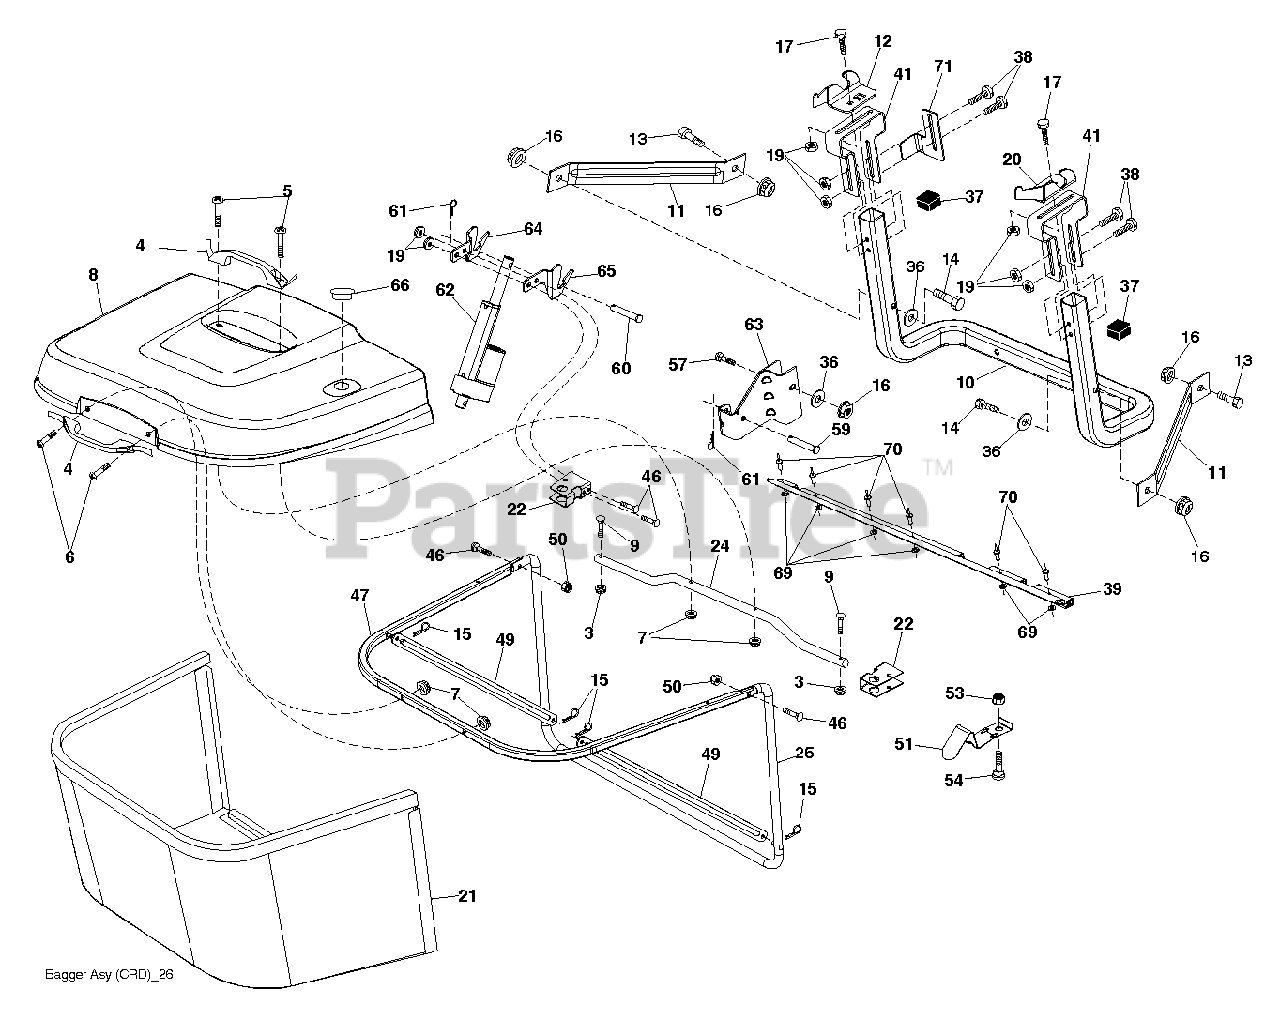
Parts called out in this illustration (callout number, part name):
3	NUT T
5	SCREW.PAN.HEAD
11	BRACKET
14	BOLT-HEX EAK
15	RETAINER-SPRNG RB
16	NUT LOCK FLG 3/8-16 UNC
17	BOLT
19	NUT LOCK HEX FLANGE 5/16-18
20	BRKT.PIVOT.RH.CRD
21	BAGGER.ASM.CRD.2007
22	BRACKET.BAGGER.SD.
24	TUBE
38	BOLT.5/16-18X2.5
39	SEAL.BAGGER.CRD
41	BRACKET.BAGGER.SD.
46	BOLT.CARRIAGE.5/16-18
50	NUT.71038.31-18.HEX.NYLOCK
53	NUT
54	BOLT
61	RETAINER M
